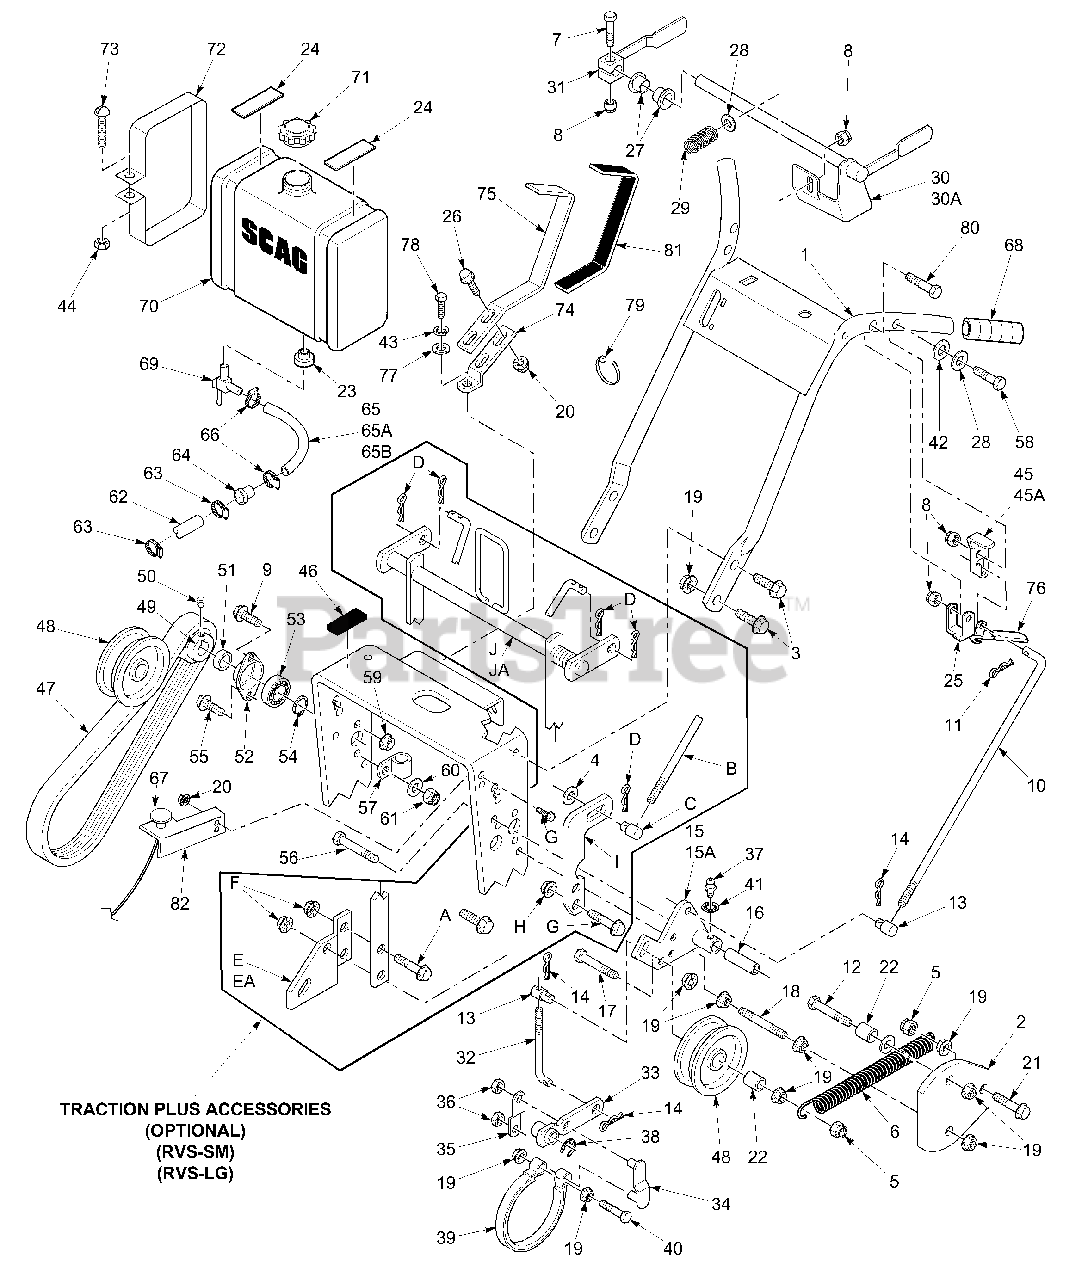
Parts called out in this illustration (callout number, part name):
1	Handle Assembly
2	Belt Guard
3	Capscrw, 3/8-16 x 1" Ser. Flange
4	Washer, 3/8" (.391 x .938 x .105)
5	Nut, 3/8-16 Elastic Stop
6	Spring, Idler
7	Bolt, 5/16-18 x 1-1/4" Hex Head
8	Nut, 5/16-18 Elastic Stop
9	Capscrew, 1/4-20 x 3/4" Hex Head
10	Control Rod, Steering
11	Hair Pin, Small
12	Bolt, 3/8-16 x 4-1/2" Hex Head
13	Swivel Joint
14	Hair Pin, Large .094 Diameter
15	Idler Bracket, RH
15A	Idler Bracket, LH
16	Idler Sleeve
17	Bolt, 3/8-16 x 3/4" Hex Head
18	Support Belt Guard
19	Nut, 3/8-16 Serrated Flange
20	Nut, 5/16-18 Serrated Flange
21	Cpscrw, 3/16-18 x 1-1/4" Ser. Flng.
22	Spacer
23	Bushing
24	Rubber Pad, (Upper)
25	Steering Lever
26	Capscrew, 5/16-18 x 1" Ser. Flng.
27	Bushing
28	Washer, 5/16 (.375 x .875 x .083)
29	Spring, Operator Presence
30	Operator Presence Lever, LH (Small Frame)
30A	Operator Presence Lever, LH (Large Frame)
31	Operator Presence Lever, RH
32	Brake Rod
33	Brake Lever
34	Brake Link
35	Brake Link Plate
36	Nut, 3/8 Push-on
37	Grease Fitting, Straight 1/4-28
38	Retaining Ring, 5/8 Ext. "E"
39	Brake Band
40	Bolt, 3/8-16 x 2" Hex Head
41	1/4" Internal Tooth Lockwasher
42	Curved Spring Washer
43	Socket Head Capscrew #8-32 x 1/2"
44	Nut, 1/4-20 Hex
45	Neutral Latch, RH
45A	Neutral Latch, LH
46	Rubber Pad (Lower)
47	Belt, Wheel Drive
48	Idler Pulley, Wheel Drive
49	Pulley, Jackshaft
50	Setscrew, Hex Socket Knurl Cup Pt. 5/16-18 (nylock)
51	Spacer, Jackshaft Pulley
52	Flange, Jackshaft Bearing
53	Bearing, Jackshaft
54	Retaining Ring, 5/8 Ext. Basic
55	Capscrew, 1/4-20 x 1" Ser. Flange
56	Bolt, 1/4-20 x 6" Carriage
58	Bolt, 5/16-18 x 2" Hex Head
59	Nut, 1/4-20 Serrated Flange
60	Flatwasher, 5/16 (.375 x .875 x .083)
61	Nut, 1/4-20 Elastic Stop
63	Fuel Hose Clamp
64	Fuel Filter
65A	Fuel Hose, 1/4" ID, 20"
66	Clamp, Fuel Hose
67	Choke Control
68	Grip, Handle
69	Valve, Fuel Shut Off
70	Fuel Tank Assy.
71	Fuel Tank Cap
72	Strap, Fuel Tank
73	Screw, 1/4-20 x 2" Rnd Hd Slotted
74	Shift Lever
75	Shift Lever Extention
76	Grip, Steering Lever
77	Washer, 3/8 (.391x .938 x .105)
78	Nut, 3/8-24 UNF
79	Cable Tie
80	Bolt, 5/16-18 x 2-1/2"
81	Grip, Shift Handle
82	Bracket, Choke Mt.
A	Capscrew, 3/8-16 x 1" Ser. Flng
B	Rod, Traction Control
C	Swivel Joint
D	Hair Pin, Large .094 Dia.
E	Mounting Brkt. LH Traction Cont.
EA	Mounting Brkt. RH Traction Cont.
F	Nut, 3/8-16 Serrated Flange
G	Capscrew, 5/16-18 x 3/4" Ser. Fig.
H	Nut, 5/16-18 Serrated Flange
I	Traction Lever, LH
J	Traction Lever Wldmnt. (Small Fm.)
JA	Traction Lever Wldmnt. (Large Fm.)
